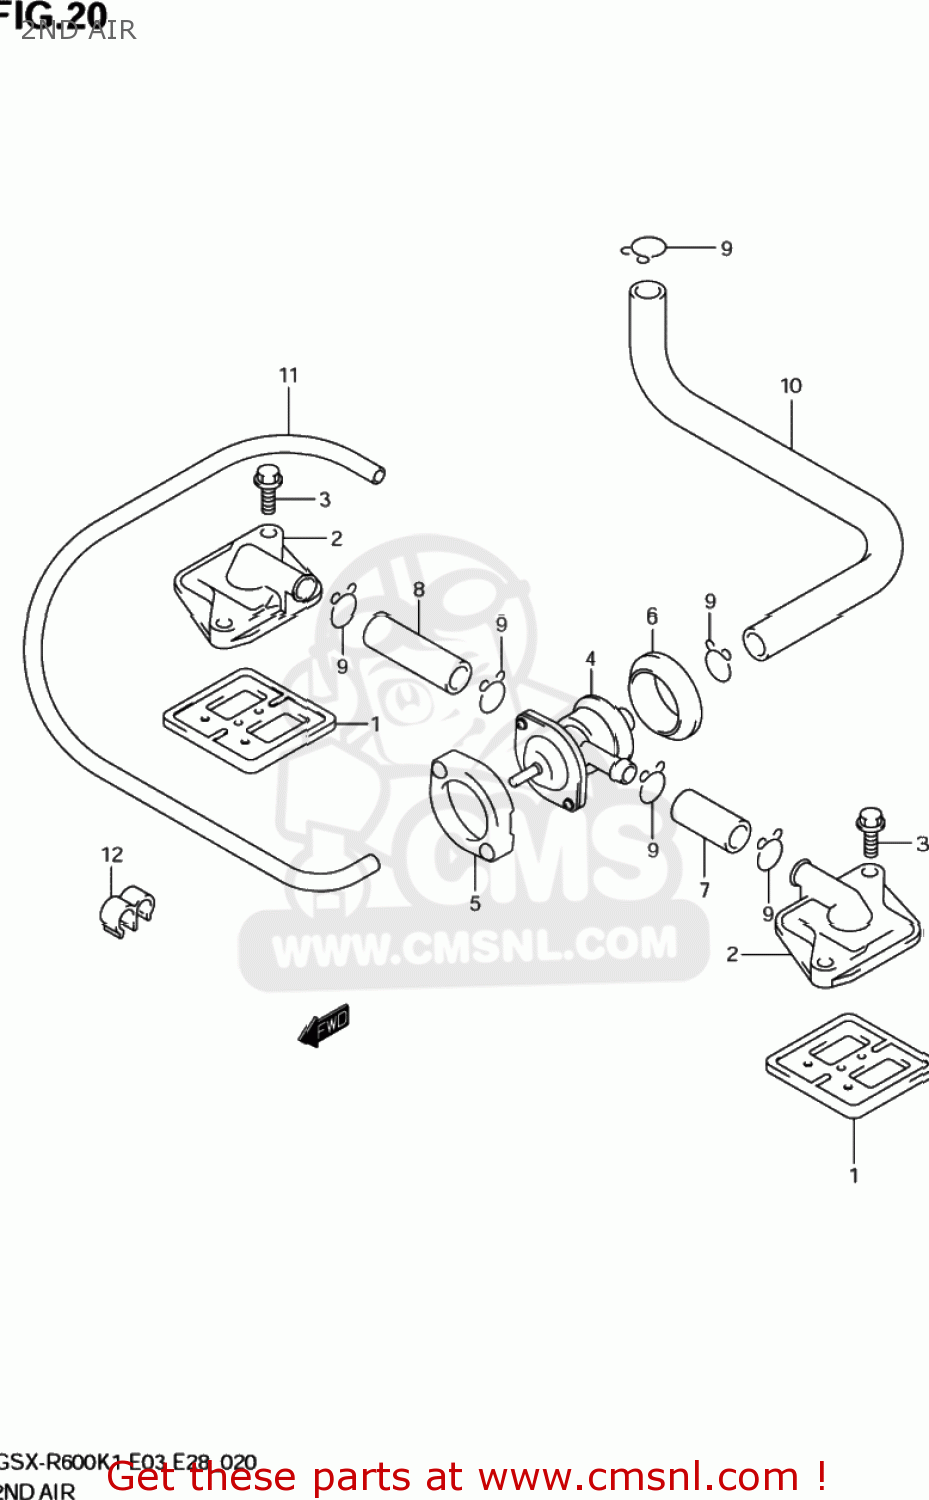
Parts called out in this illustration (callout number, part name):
1	VALVE ASSY,2ND AIR REED
2	COVER,2ND AIR REED VALVE
3	BOLT,SECOND AIR REED VALVE
4	VALVE ASSY,AIR CUT
5	CUSHION,AIR CUT VALVE UPR
6	CUSHION,AIR CUT VALVE LWR
7	HOSE(11X16X600)
8	HOSE(11X16X600)
9	CLIP
10	HOSE,2ND AIR CLEANER
11	HOSE(3.5X7.5X600)
12	CLAMP
